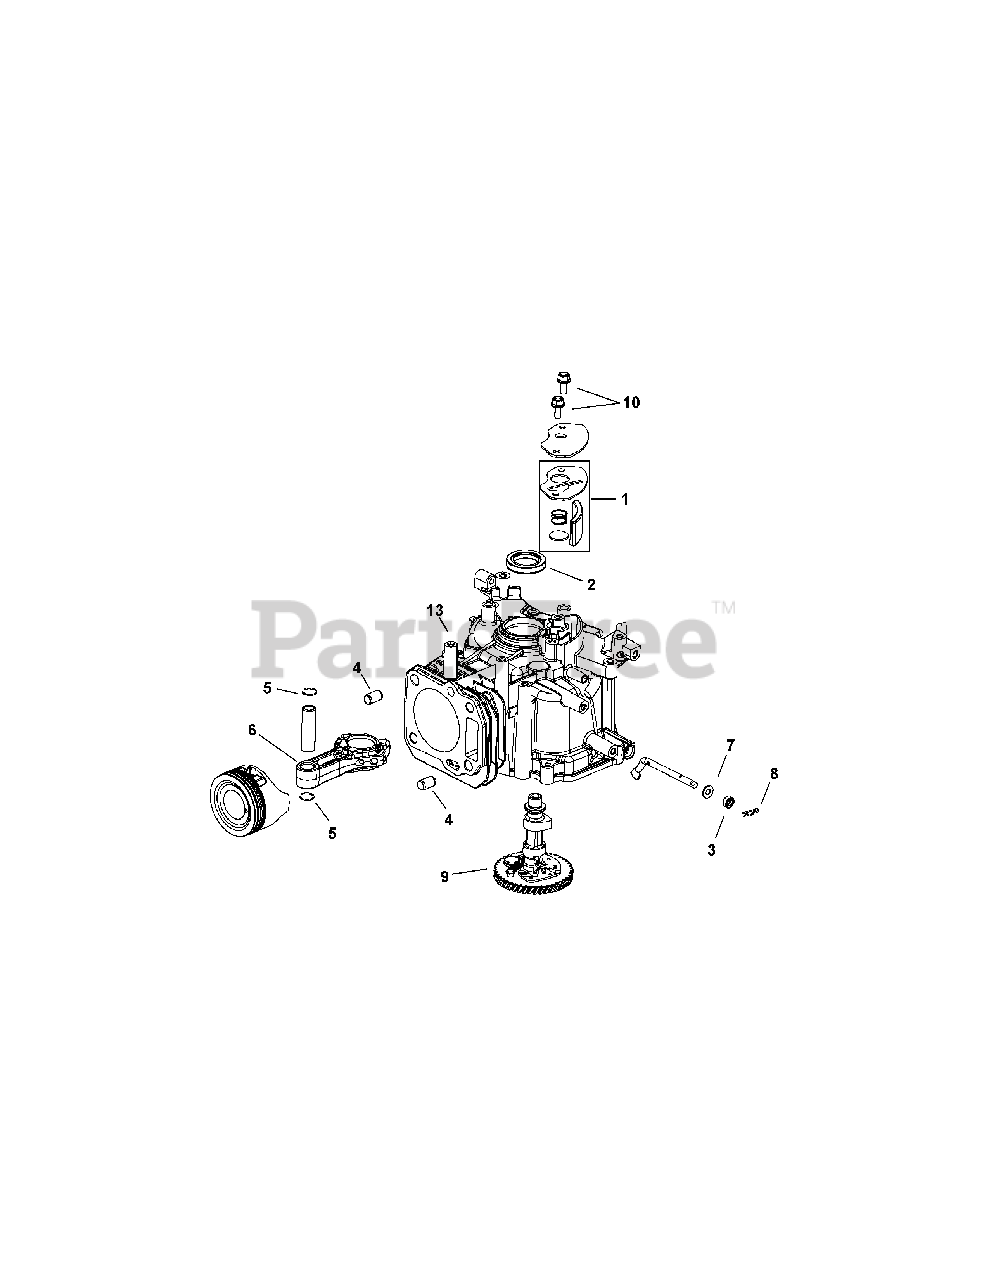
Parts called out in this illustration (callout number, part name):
1	Breather Filter Kit
4	Cylinder Head Dowel
5	Piston Pin Retainer
6	Connecting Rod
7	Flat Washer (Dia. 13mm O.D.)
8	Governor Shaft Clip
9	Camshaft Assembly
10	Hex Flange Screw, M6
